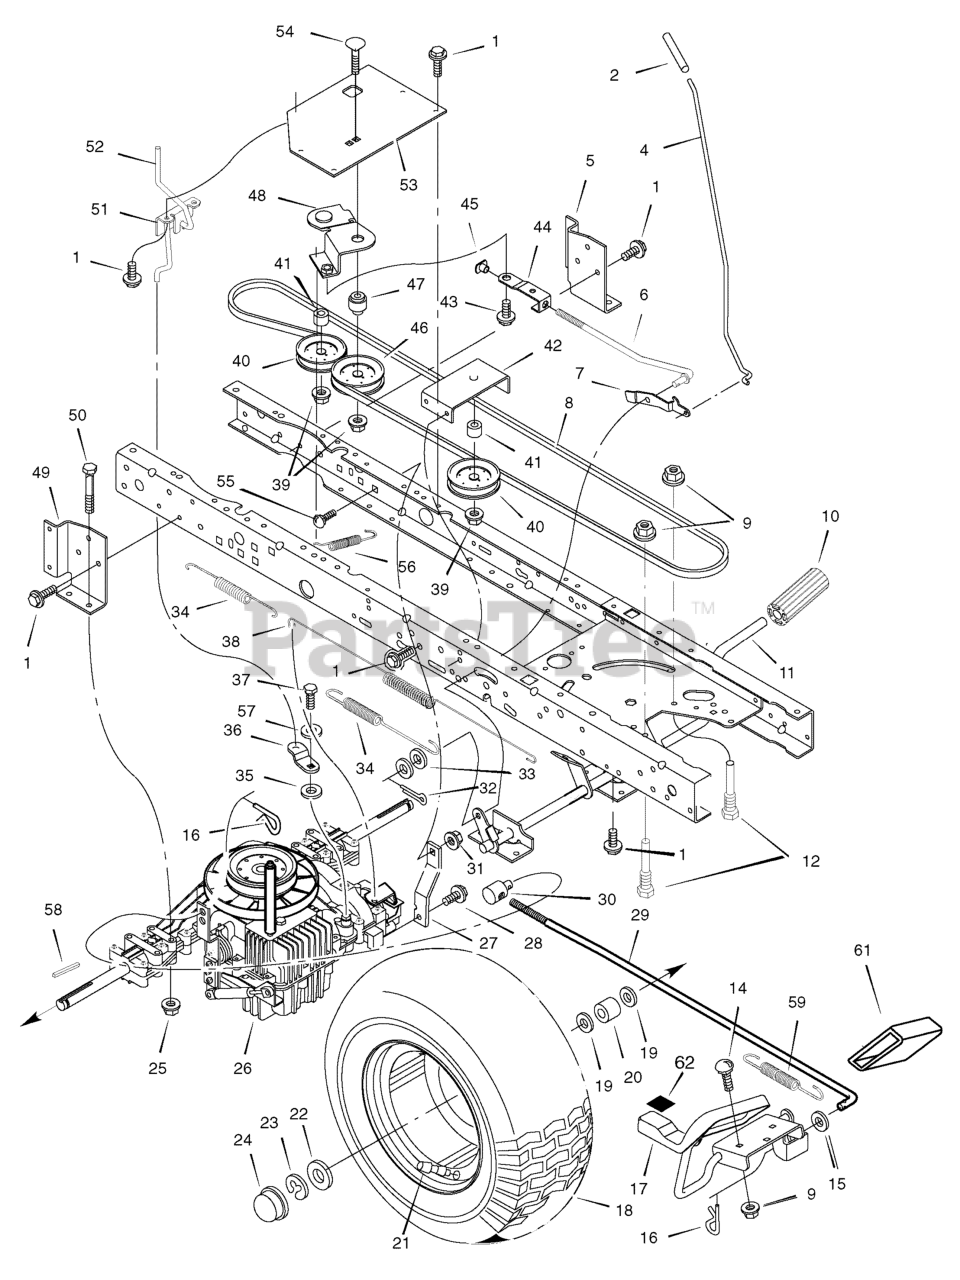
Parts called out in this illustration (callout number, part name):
2	Grip, Parking Brake
4	Rod, Parking Brake
5	Bracket, Left Transaxle
6	Rod, Clutch
7	Latch, Parking Brake
8	V-Belt, Drive
9	Nut, Flange
10	Pedal, Brake/Clutch
11	Assembly, Brake Pedal
12	Screw, Guide
14	Bolt, Carriage
16	Pin, Hair
17	Pedal Assembly, Hydro
18	Wheel & Tire Assy, Rear
21	Stem, Valve
23	E--Ring
24	Cap, Hub
25	Nut, Centerlock
26	Transaxle, Peerless Hydro **
27	Strap, Torque
29	Rod, Control
30	Nut, Adjusting
31	Nut, Centerlock
32	Pin, Cotter
34	Spring, Extension
36	Arm, Disconnect
37	Capscrew
38	Spring, Brake
39	Locknut, Flange
40	Pulley, Idler
42	Bracket, Idler Assembly
43	Bolt, Shoulder
44	Link, Clutch
45	Nut, Tee
46	Pulley, Idler
47	Bushing, Pivot
48	Arm Assembly, Idler
49	Bracket, Right Transaxle
50	Bolt, Hex
51	Bracket, Dump Valve
52	Rod, Roll Release
53	Bracket, Idler Pivot
54	Bolt, Carriage
55	Bolt, Carriage
56	Spring, Clutch
58	Key, Square 3/16"
61	Pad, Hydro Pedal
62	Mat, Toe-Reverse
